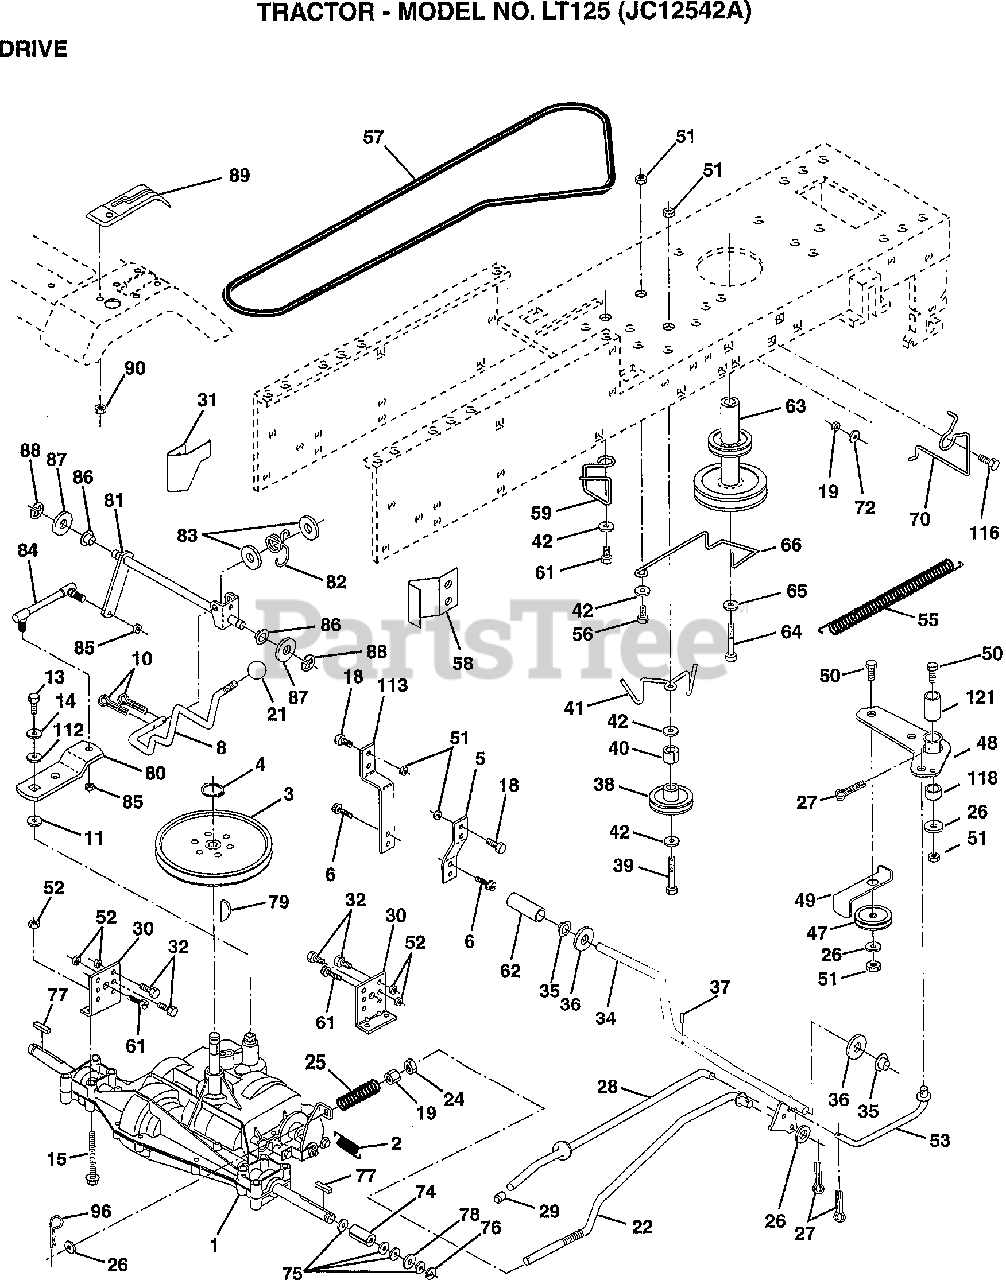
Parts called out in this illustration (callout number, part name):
1	TRANSAXLE, PEERLESS
4	RING, RETAINER
6	SCREW THDROL 5/16-18 X 3/4 TYT
10	PIN COTTER 1/8 X 1 CAD
13	BOLT 1/4-28 GR 8 W/PATCH
14	WASHER, LOCK 1/4
15	BOLT HEX 5/16-18 GA 5
18	BOLT FIN HEX 3/8-16 X 1
19	LOCKNUT
24	NUT HEX JAM 3/8-16 UNC
26	WASHER 13/32 X 13/16 X 16 GA
27	PIN COTTER 1/8 X 3/4 CAD
32	BOLT, HEX 5/16-18 X 3/4
36	WASHER 21/32 X 1 X 16 GA
39	BOLT FIN HEX 3/8-16 X 2-3/4
42	WASHER
50	BOLT HEX HD 3/8-16 X 1-1/2
51	NUT, CROWNLOCK 3/8-16
52	LOCKNUT, CROWN 5/16-18
56	BOLT, HEX 3/8-16 X 1-1/4
61	SCREW THDROL 3/8-16X3/4 TY-TT
64	BOLT HEX
65	WASHER LOCK HVY HLCL SPR 7/16
72	WASHER 13/32 X 1-1/4 X 12 GA
76	E-RING #5133-75
81	SHAFT ASM CROSS
83	WASHER 17/32 X 3/4 X 16 GA
87	WASHER 21/32 X 1-1/4 X 16 GA
88	RING CLIP #5304-62
112	WASHER 9/32 X 3/4 X 10 GA
116	BOLT RDHD SQ NECK 3/8-16 X 1.25
